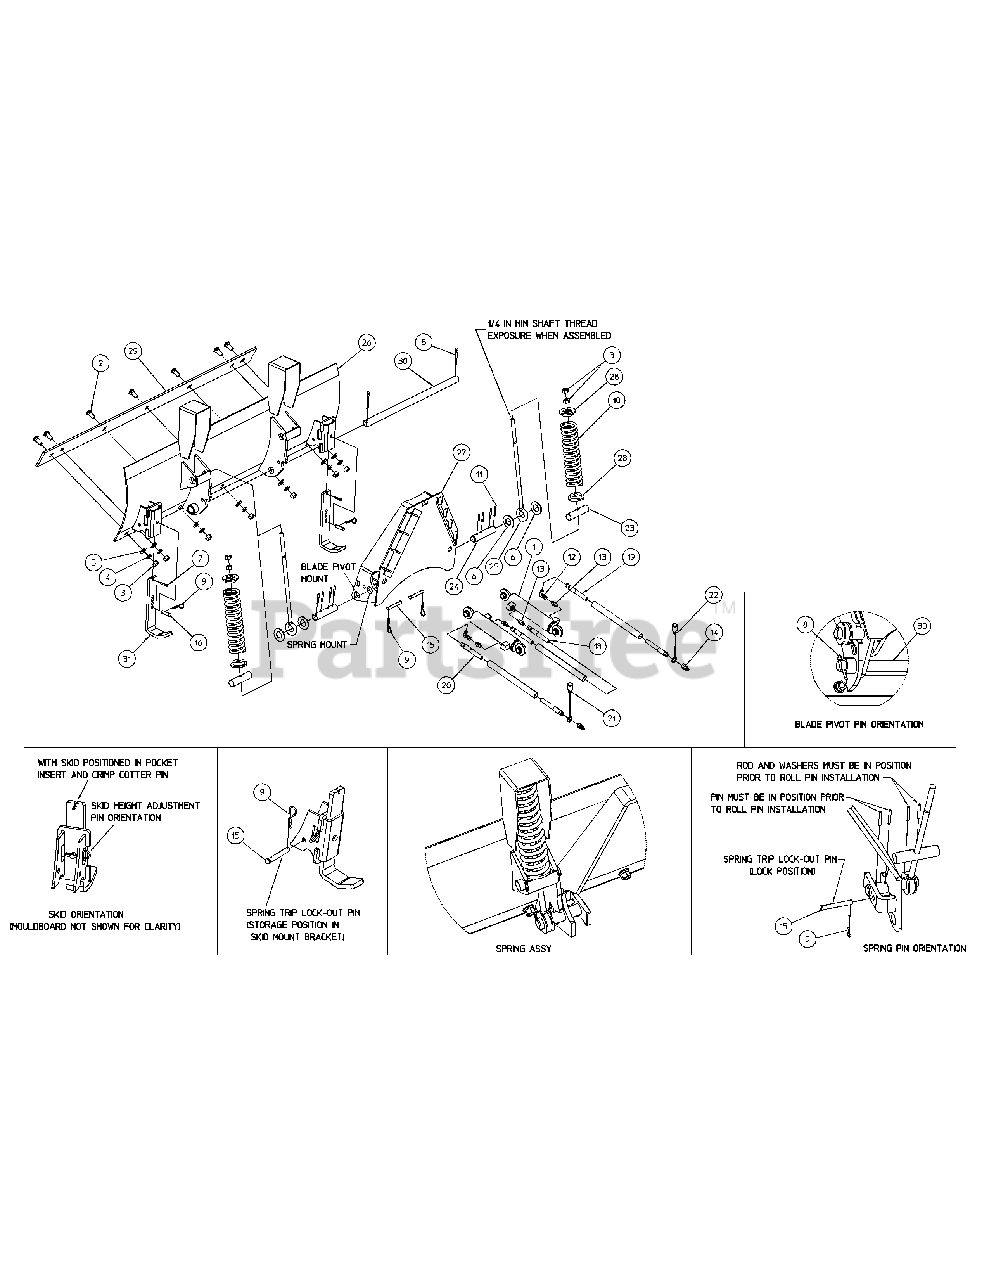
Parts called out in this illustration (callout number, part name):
1	ASSY-HYD CYLINDER
2	CARRIAGE BOLT 5/8-11X1.5
3	NUT HEX 5/8-11
4	LOCK WASHER 5/8
5	FLAT WASHER 5/8 HARDENED
6	FLAT WASHER 1-1/4 SAE
7	COTTER PIN 1/4 X 1
8	COTTER PIN 5/16 X 2-1/2
9	HAIR PIN CLIP
10	COMPRESSION SPRING
11	ROLL PIN 1/4 X 2
13	UNION STRAIGHT
14	COUPLER NOSE
15	CLEVIS PIN 1/2 X 3-1/2
16	CLEVIS PIN 1/2 X 1-3/4
17	HYDRAULIC FLUID
18	HYD HOSE WITH SLEEVE 1/4 X 20
19	HYD HOSE WITH SLEEVE 1/4 X 63
20	HYD HOSE WITH SLEEVE 1/4 X 75
21	DUST CAP GREEN
22	DUST CAP YELLOW
23	SPRING PIVOT PIN
25	EYE BOLT (SPRING MOUNT)
26	60" MOULDBOARD WITH DECALS
27	MOUNT WELDMENT
28	SPRING CAP WELDMENT
29	60" CUTTING EDGE PLATE
30	BLADE PIVOT PIN
31	SKID PLATE
